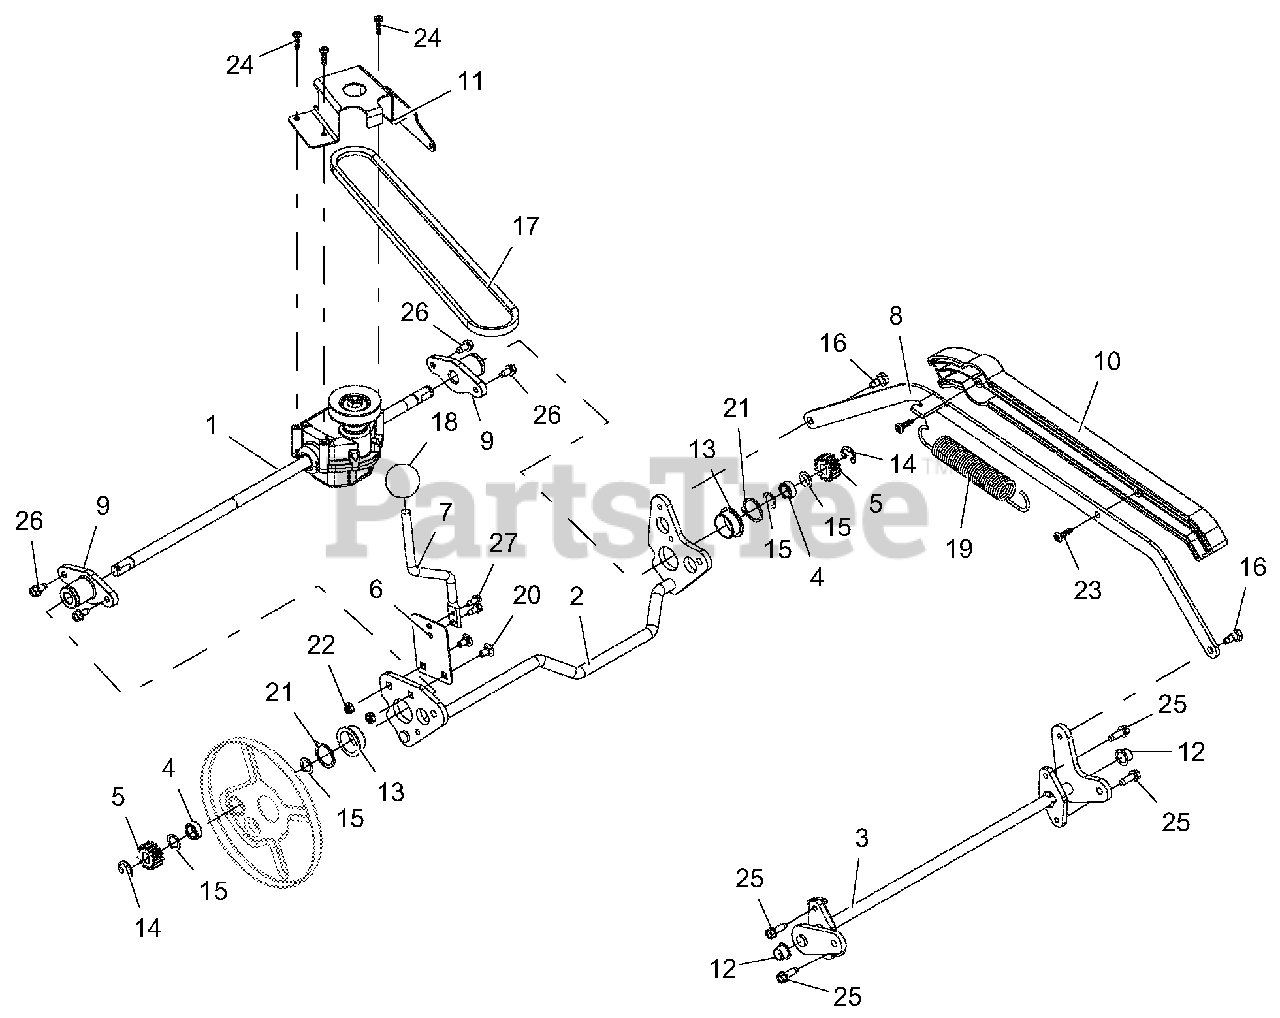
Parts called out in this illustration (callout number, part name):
1	TRANSAXLE, AUTOMATIC, LM, 9:1
2	WLDMT, LM REAR AXLE
3	WLDMT, LM FRONT AXLE
4	SPCR, PM .500ID X .75OD X .321
5	GEAR, PINION , LM WHEEL DRIVE
6	PLATE, HOC SPRING
7	LEVER, HOC ADJUST
8	LINK, HOC CONNECT
9	HUB, LM REAR AXLE
10	COVER, LINK ROD
11	BRKT, TRANS BELT GUIDE
12	BUSHING, POLYLINER - .50 SPLIT
13	BSHG, FLANGE 1.0x1.125x.50x1.375
14	RG-RTNG-EXT .500X.042 (E)
15	WASHER-FLAT-STL, .500 X .750 X .020
16	BOLT, SHLDR .320X.210X.25-20 SELF-TAPPING
18	KNOB,BALL -BLACK 1.47" .375-16
19	SPRG, EXTENSION
20	BLT-RDHDSQNK .25-20X.50 G5 Y
21	RG-RTNG-EXT 1.00X.042
22	@NUT-LK-CTR-JAM .25-20 YWZC
23	SCR-TAP #12-14X.75 PLASTITE BLZC
24	SCR-TAP #10-14X.75 PLASTITE BLZC
25	SCR-TAP .25-20X.75 HWH TR YWZ
26	SCR-TAP .25-20X.50 HWH TR YWZ
27	SCR-TAP 12-24X.50 HWH TR YWZC
